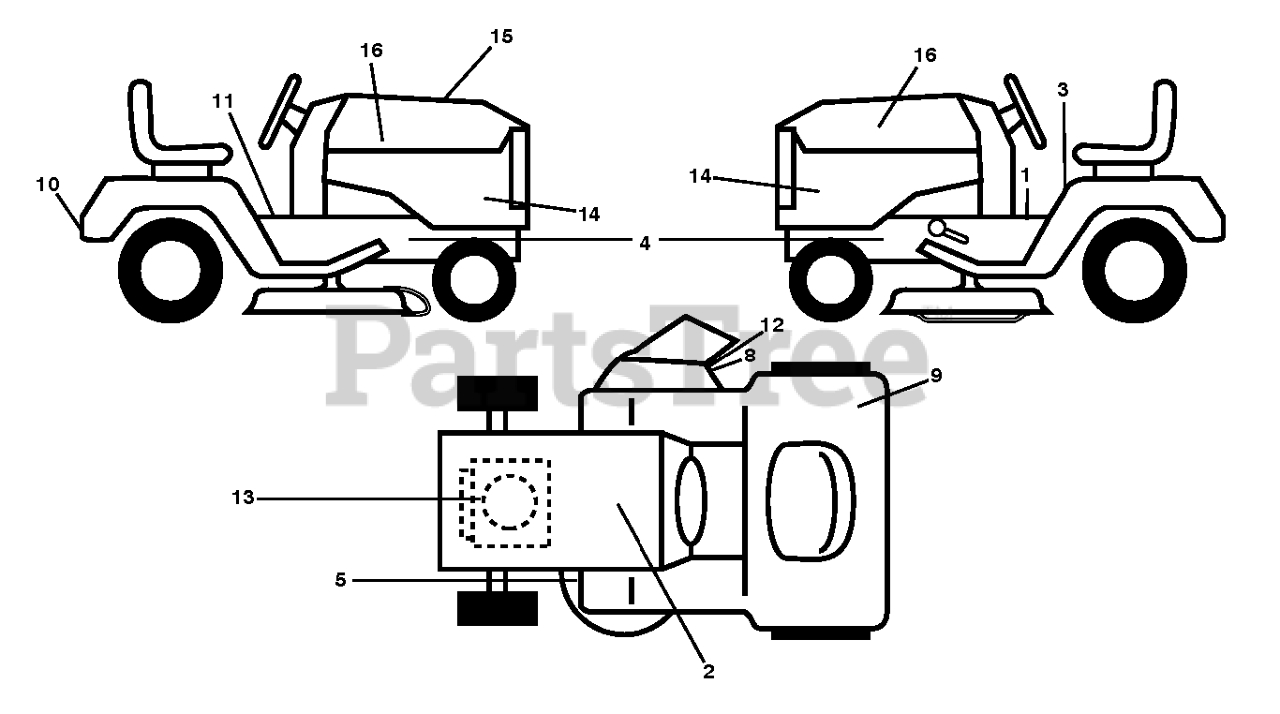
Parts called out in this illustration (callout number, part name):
1	DECAL PARK BRAKE
2	DECAL BTRY SYMBOLS
3	LABEL
5	DECAL V BELT SCHEMATIC
8	DECAL, DEFLECT WARNING
9	DECAL
10	DECAL
11	DECAL
12	DECAL.INTERNATIONL.CUTFINGER
13	DECAL
16	DECAL.BADGE.170MM.TEXTLOGO.
